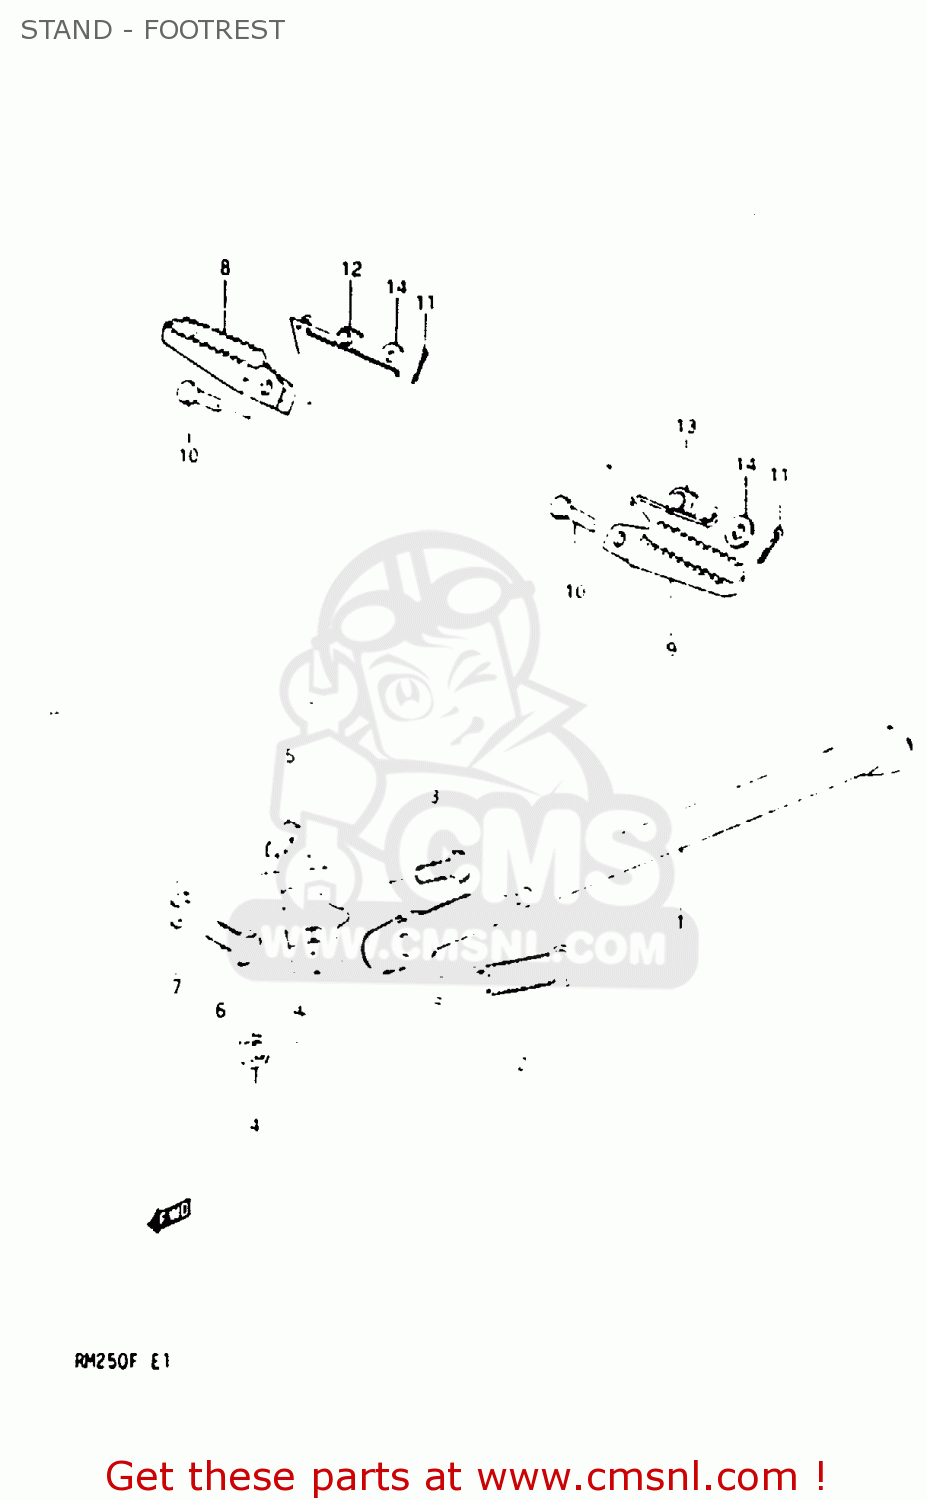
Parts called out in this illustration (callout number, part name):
1	STAND,SIDE
2	SPRING
3	BOLT(10X30)
4	NUT
5	BRACKET,SIDE STAND
6	BOLT(10X19)
7	LOCK WASHER
8	FOOTREST
9	FOOTREST
10	PIN
11	PIN 20X20
12	SPRING,FOOTREST,RIGHT
13	SPRING,FOOTREST LH
14	WASHER
